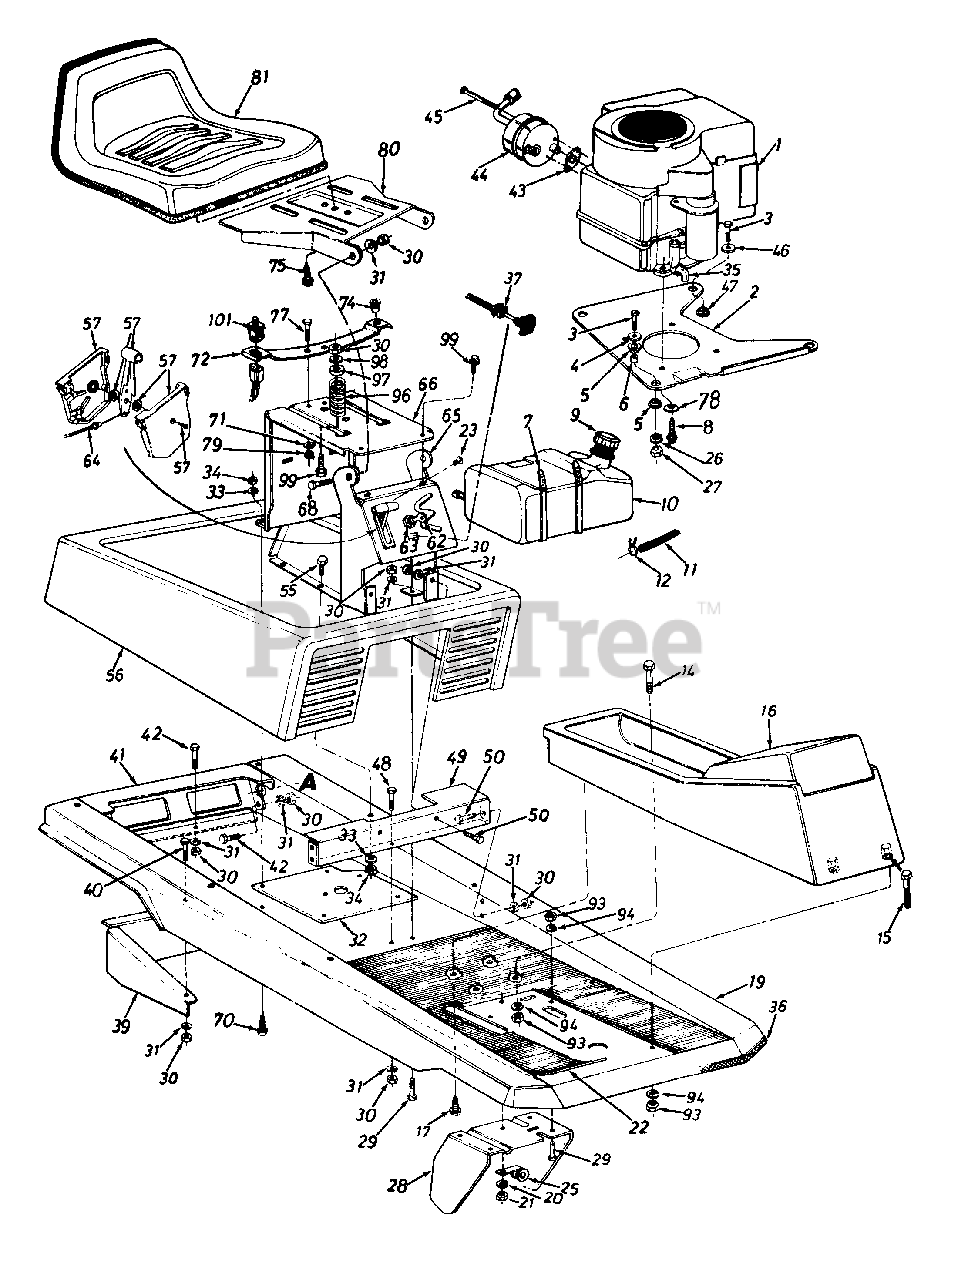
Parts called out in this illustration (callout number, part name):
1	Engine
2	Engine Mounting Plate
3	Hex Bolt 5/16-24 x 1.25" Lg.
4	Fl - Wash. .330" I.D. x 1.125" O.D.
5	Engine Mounting Grommet
6	Spacer .315" I.D. x .50" O.D. x .520" Lg.
7	Cable Tie 30.6" Lg.
8	Hex Wash. Hd. Self - Tap Scr. 3/8-16 x 1.25" Lg.
9	Gas Cap
10	Fuel Tank
11	Gas Line - 26 Inches
12	Hose Clamp - 1/2" O.D. Tube
14	Hex Bolt 5/16-18 x 1.75" Lg.
15	Hex Bolt 5/16-18 x 2.0" Lg.
16	Front Console
17	Plastite Scr. 5/16 x 1.25" Lg.
19	Main Frame
20	L - Wash. 5/16" I.D.
21	Hex Nut 5/16-18 Thd.
22	Floor Mat
23	Truss Mach. AB-Tap Scr. #10 x .50" Lg.
25	Clamp
26	L - Wash. 5/16" I.D."
27	Hex Nut 5/16-24 Thd."
28	Clutch - Brake Pedal Ass'y.
29	Hex Bolt 5/16-18 x .75" Lg
30	Hex Nut 5/16-18 Thd.
31	L - Wash. 5/16" I.D.
34	Hex Nut 1/4-20 Thd.
35	90ø Elbow Male To Female
36	Trim Strip 57" Lg.
37	Choke Control
43	Exhaust Gasket
44	Muffler Ass'y.
44	Spark Arrester
45	Shld, Bolt
46	Fl - Wash. .33" I.D. x 1.25" O.D.
47	Flange Wash. .32" I.D. x .75" O.D.
48	Hex Bolt 5/16-18 x .75" Lg.
49	Seat Support & Frame Brkt.
50	Hex Bolt 5/16-18 x .75" Lg.
55	Hex Bolt 1/4-20 x .50" Lg.
62	Ignition Key
63	Ignition Switch
64	Throttle Control Wire 35" Lg.
68	Shld. Bolt .437" Dia. x .268" Lg.
70	Hex Tap Scr. 1/4-20 x 1.0" Lg.
71	L - Wash. 5/16" I.D.
72	Seat Spring
74	Grommet
75	Hex Wash. Hd. Tap Scr. 3/8-16 x 3/4" Lg.
77	Hex Bolt 5/16-18 x .75" Lg.
78	Bell - Wash. .345" I.D. x .88" O.D.
79	Hex Cent. L - Nut 5/16-18 Thd.
81	Seat Ass'y.
93	Hex Nut 5/16-18 Thd.
94	L - Wash. 5/16" I.D.
96	Compression Spring 2.6" Lg.
97	Bushing
98	Fl - Wash. .344" I.D. x .875"
99	Hex Bolt 5/16-18 x 1" Lg. (Gr. 5)
101	Seat Switch
